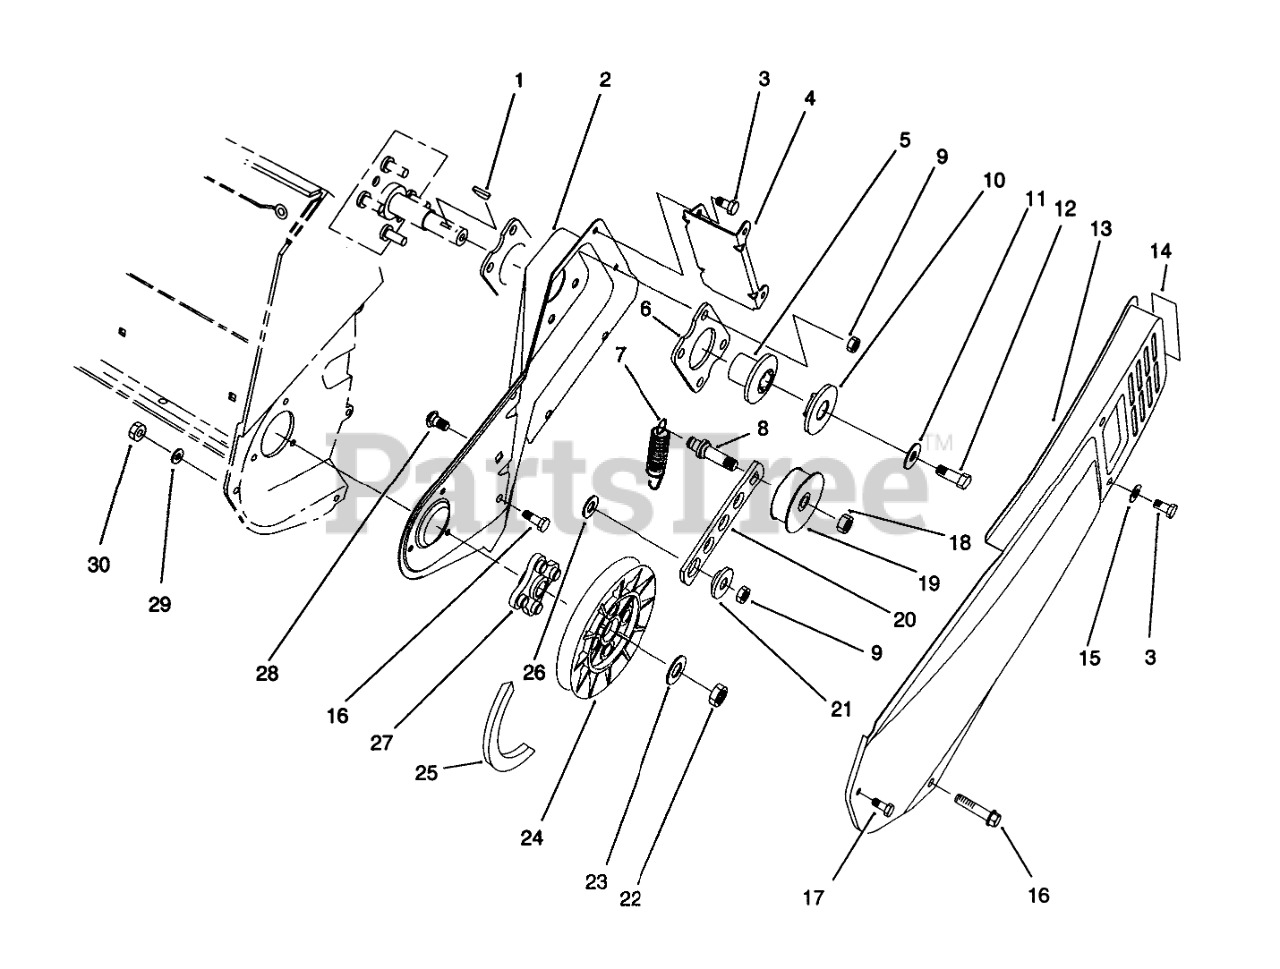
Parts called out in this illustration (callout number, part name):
1	KEY-WOODRUFF
2	Sideplate-LH
3	SCREW-HWH
4	Bracket-Cover
5	Hub-HALF SHEAVE
6	Plate Engine
7	SPRING-EXTENSION
8	PIN-IDLER
9	NUT-LOCK, NI
10	CAP-HALF SHEAVE
11	WASHER-FLAT
12	SCREW-HH
13	Cover-Belt
14	Decal-Hot
15	WASHER-FLAT
16	SCREW-PLASTIC
18	NUT-LOCK, NI
19	PULLEY-IDLER
20	ARM-IDLER
21	BUSHING-IDLER
22	NUT-LOCK, NI
23	WASHER-FLAT
24	PULLEY-DRIVEN
25	V-BELT
26	WASHER
28	SCREW-CARR
29	WASHER-FLAT
30	NUT-LOCK, NI
